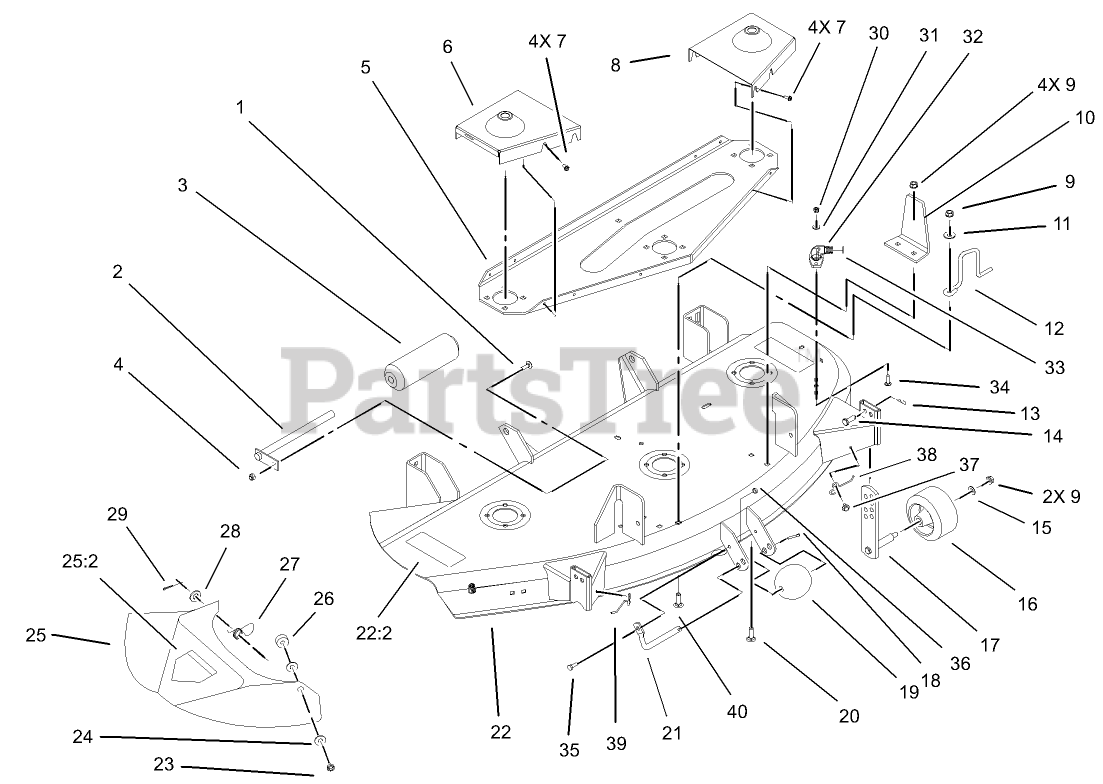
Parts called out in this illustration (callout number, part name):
1	BOLT-CARR
2	ROLLER-SHAFT
3	ROLLER-ANTI SCALP
4	NUT-LOCK, NI
5	PLATE-REINFORCE
6	COVER-BELT, RH
7	SCREW-HHFTF
8	COVER-BELT, LH
9	NUT-LOCK, NI
10	BRACKET-GUIDE
11	WASHER
13	PIN-HAIR
14	PIN-CLEVIS
15	WASHER-FLAT
17	GAGE-WHEEL
18	PIN-COTTER
19	ROLLER
20	BOLT-CARR
21	SHAFT-ROLLER
22	48IN DECK/DECAL ASM
22:2	DECAL-DANGER
23	NUT-HJ
24	WASHER
25	CHUTE ASM
25:2	DECAL-DANGER
26	BUSHING-PIVOT
27	SPRING-DEFLECTOR
28	WASHER-FLAT
29	PIN-COTTER
30	NUT-LOCK, NI
31	WASHER-FLAT
33	O-RING
34	BOLT-CARR
35	SCREW-HH
36	NUT-LOCK, NI
37	SCREW-HHFTF
39	SPRING-GAGE WHEEL, RH
40	SCREW-CARR
